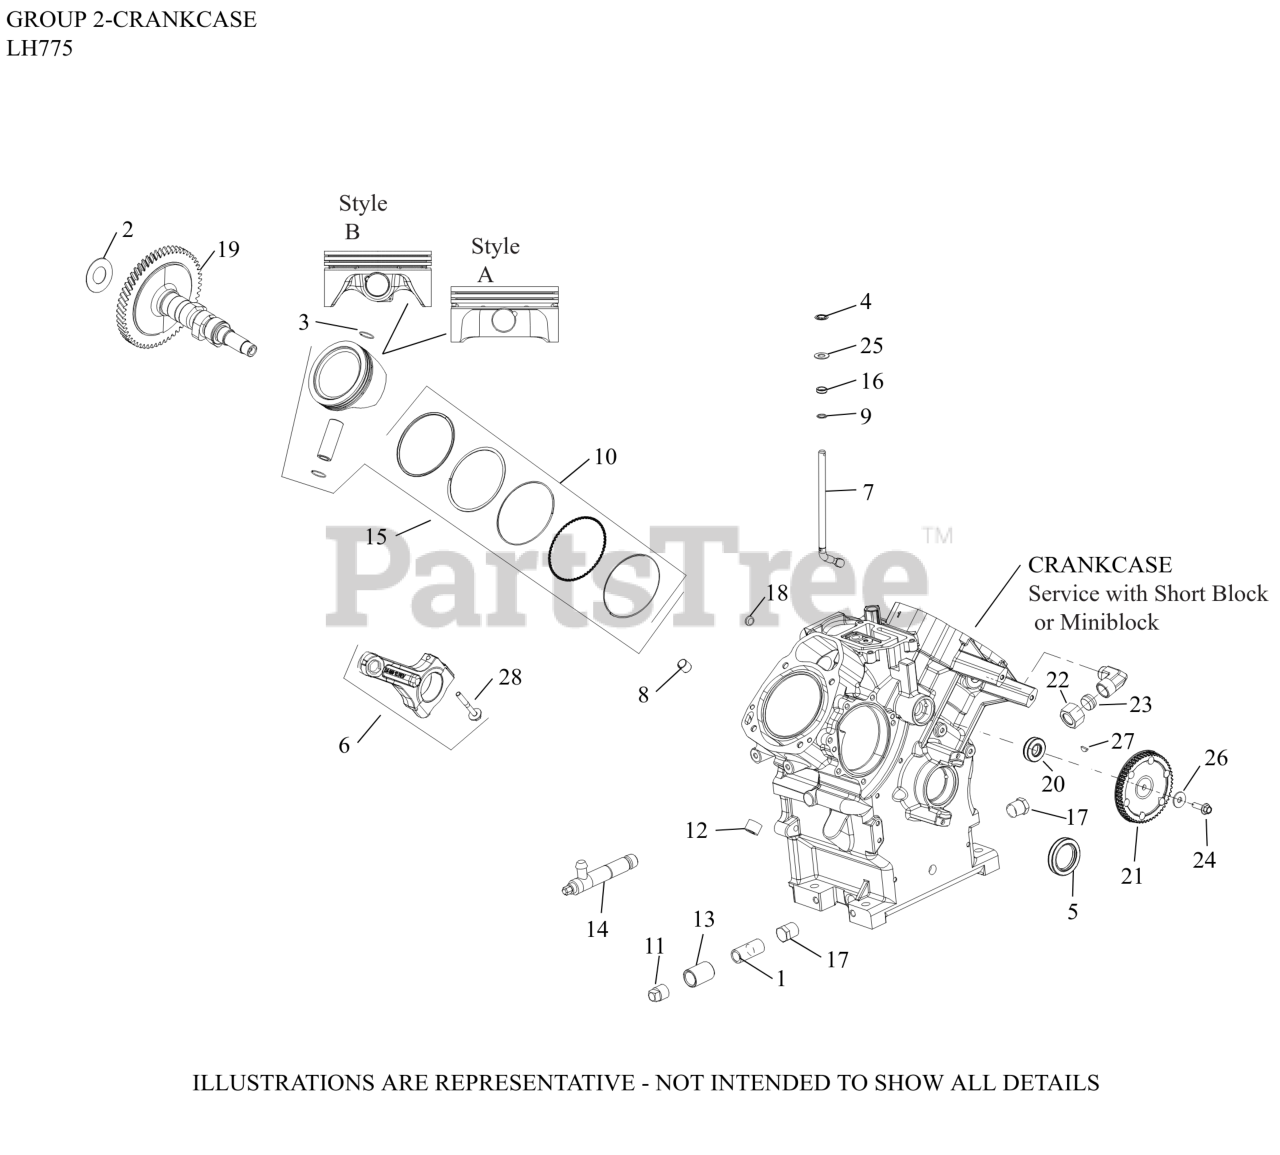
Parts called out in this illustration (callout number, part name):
2	SHIM, CAMSHAFT (WHITE .028")
2	SHIM, CAMSHAFT (BLUE .03")
2	SHIM, CAMSHAFT (RED .032")
2	SHIM, CAMSHAFT (YELLOW .034")
2	SHIM, CAMSHAFT (GREEN .036")
2	SHIM, CAMSHAFT (GRAY .038")
2	SHIM, CAMSHAFT (BLACK .04")
3	RETAINER, PISTON PIN
4	RETAINER, RING
5	SEAL, OIL (HELIX LIP)
6	ROD, ASSEMBLY CONNECTING
7	SHAFT, GOVERNOR CROSS
8	PIN, LOCATING
9	WASHER, FLAT 11/32"
10	RING DISC USE PISTON ASSY PER SPEC
10	RING SET(.08)STYLE A-1.5mm Tp RING THICK
10	RING SET(.25)STYLE A-1.5mm Tp RING THICK
10	RING SET(.50)STYLE A-1.5mm Tp-(#DSC)
10	RING SET(STD)STYLE B-1.2mm Tp RING THICK
10	RING SET(.08)STYLE B-1.2mm RING THICK
10	RING SET(.25)STYLE B-1.2mm Tp RING THICK
10	RING SET(.50)STYLE B-1.2mm Tp RING THICK
12	PLUG, PIPE CTSK 3/8"
14	VALVE, OIL DRAIN MEDIUM
15	KIT,PSTN/RNG STYLE A(STD)(#2587406S)
15	KIT,PSTN/RNG STYLE A(.08)
15	KIT,PSTN/RNG STYLE A(.25)USE 2587411-S
15	KIT,PSTN/RNG STYLE A(.50)(#2587404S)
15	KIT,PSTN/RNG STYLE B(STD)
15	KIT,PSTN/RNG STYLE B(.08)
15	KIT,PSTN/RNG STYLE B(.25)
15	KIT,PSTN/RNG STYLE B(.50)
16	SEAL, GOVERNOR CROSS SHAFT
18	PLUG, CUP
19	KIT, CAMSHAFT-EFI
20	SEAL, CAMSHAFT
21	SPROCKET, CAMSHAFT
24	SCREW, FLG M6x1.0x20
25	WASHER, FLAT 9 MM
26	WASHER, FLAT 1/4"
27	KEY, 3/32" X 3/8"
28	KIT, ROD BOLTS-(#25086677S)
